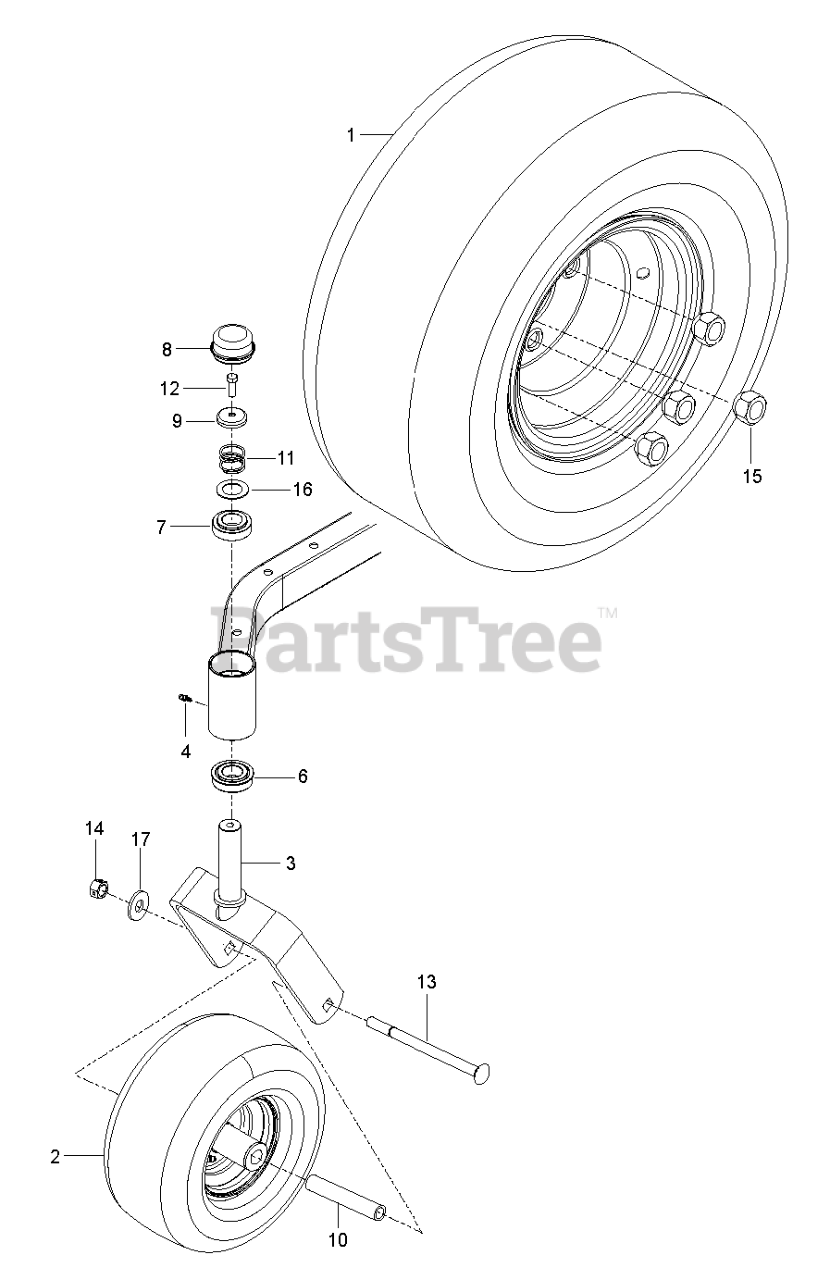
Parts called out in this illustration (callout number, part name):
1	WHEEL CARLSTAR 18X9.5-8" SILVE
2	WHEEL ASSY, WIDE, RZ
3	YOKE.PNT.CASTER.ORG
4	ZERK, 3/16, DRIVE IN
6	BEARING FLANGED
7	BUSHING, CASTER
8	GREASE CAP
9	CASTER.PLUG
10	SPACER.PIVOT
11	SPRING, CASTER
12	5/16-18X1 HHB G5W/NY
13	RHSNB 1/2-13 X 7.5
14	NUT. 1/2-13 HEX CNTRLK GR 5 ZD
15	NUT.1/2-20.UNF-2B.GR.8.YL
16	WASHER, 1.025 ID X 1.64
17	WASHER.9/16 X 1 3/8 X 12 GA.
